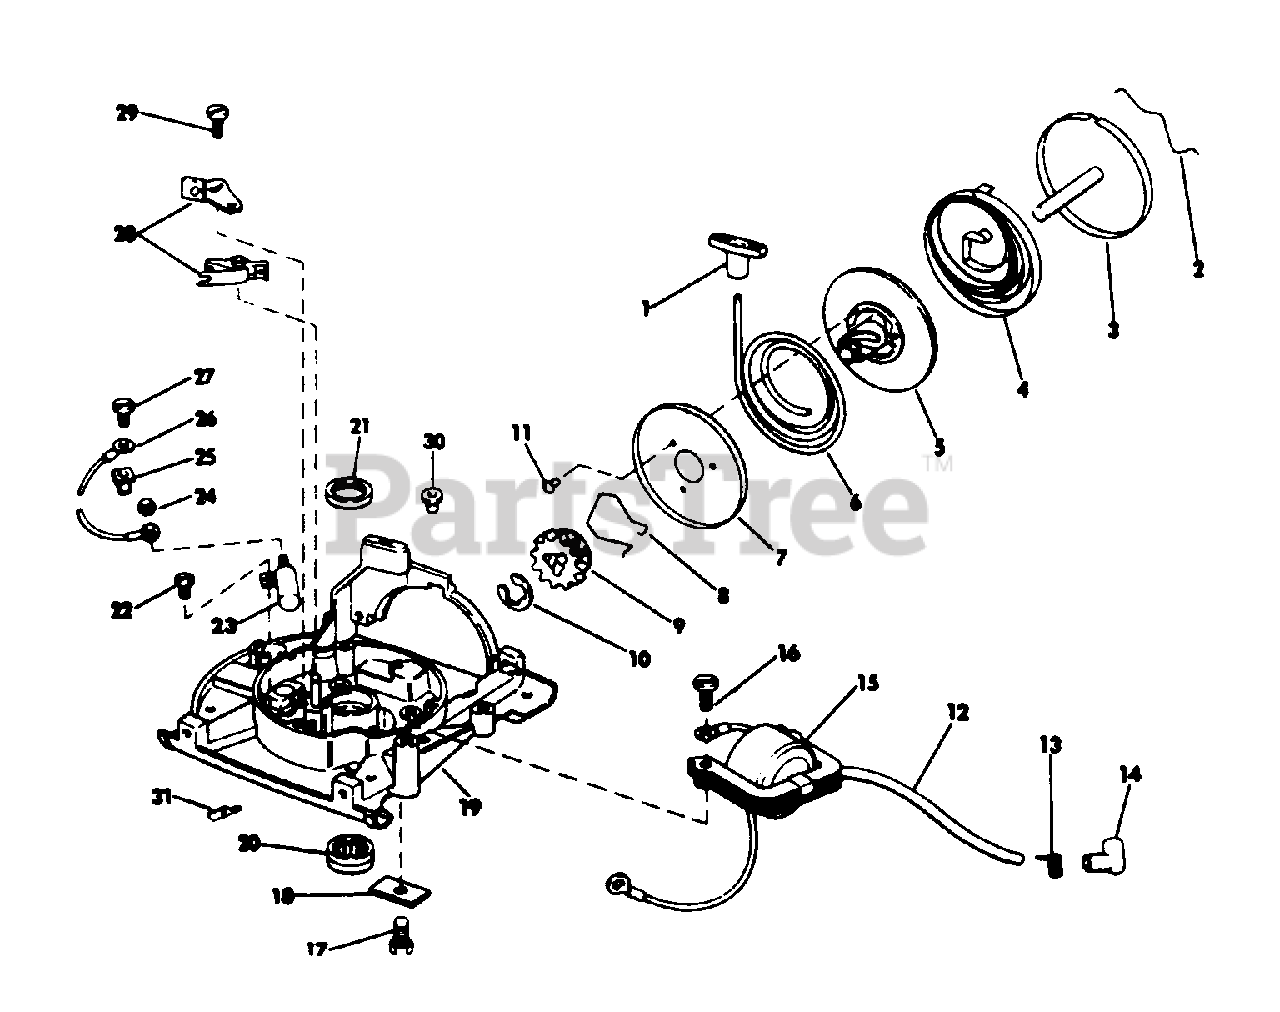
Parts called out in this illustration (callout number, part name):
1	Handle-Starter
2	Spring-Starter Rope Retainer
3	Spring-Cup-Pin Assy.
4	Spring-Starter
5	Pulley-Starter
6	Rope-Starter
7	Plate-Starter Pulley
8	Spring-Starter Pinion
9	Pinion-Starter
10	Retainer-Push-On
11	Screw-Threaded Cutting Starter
12	High Tension Lead Assy.
13	Terminal-Spring
14	Cover-Rubber
15	Coil & Lamination Assy.
16	Scr.-Lamination Mtg.
17	Scr.-Starter Attach.
18	Clamp-Starter Pin
19	Arm. Pl., Brg & Oil Seal Assy.
21	Oil Seal
22	Scr.-Cond. Mtg.
23	Cond. & Nut Assy.
25	Grommet-Nylon
26	Terminal & Lead Assy.
27	Scr.-Shut-Off Sw.
28	Brkr. Base & Arm Assy.
29	Scr.-Breaker Base
30	Grommet
